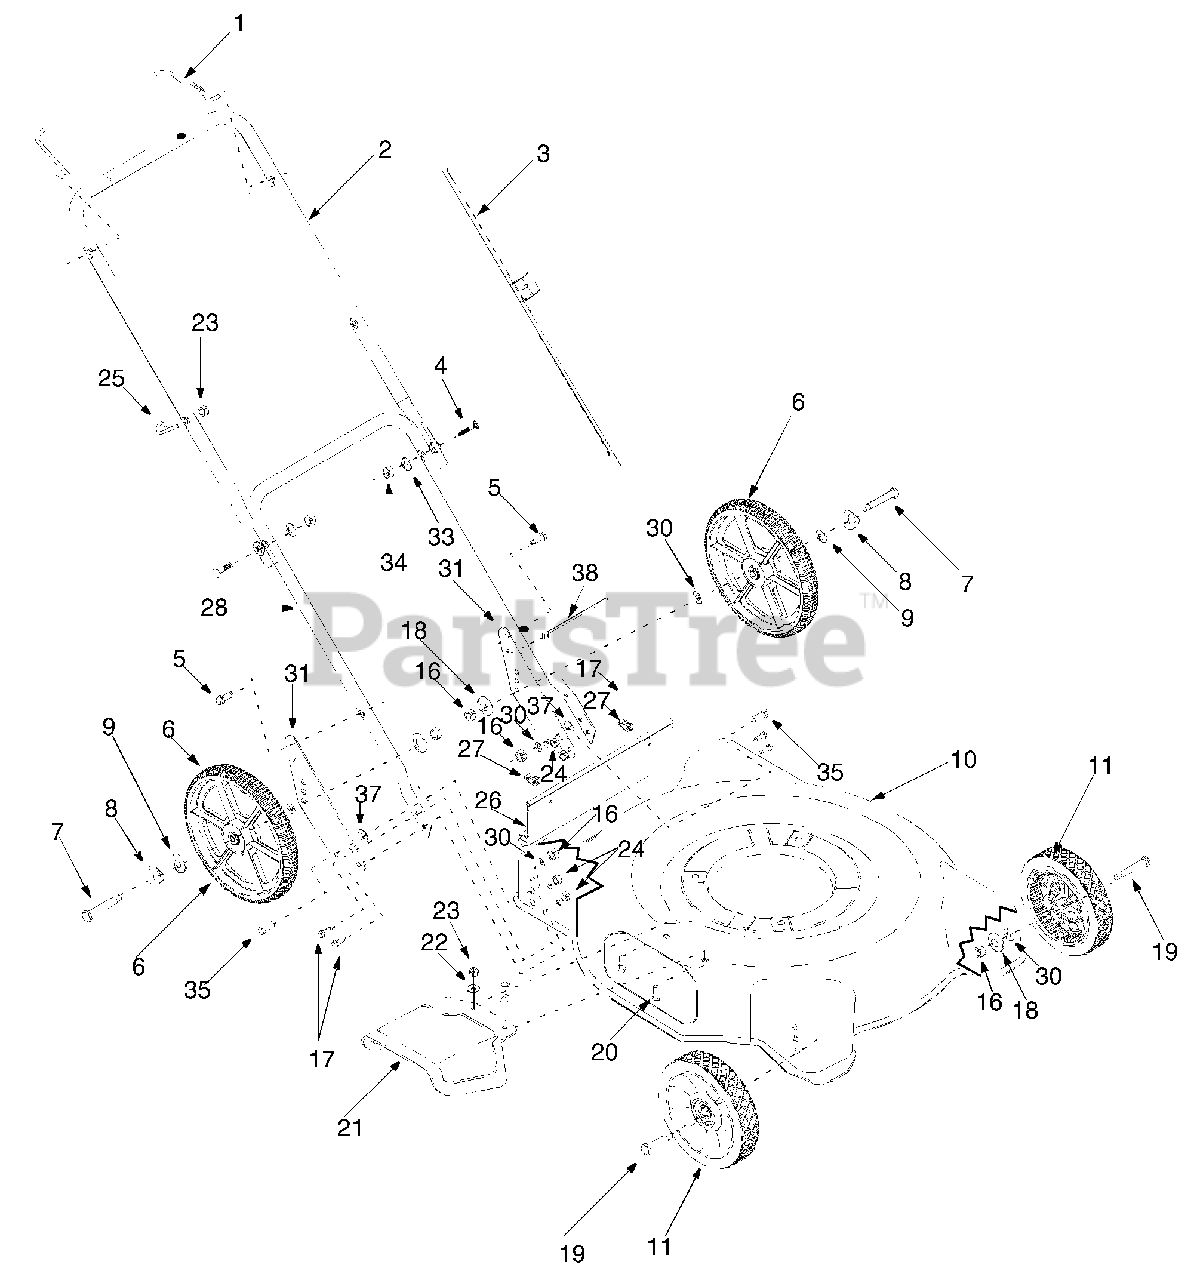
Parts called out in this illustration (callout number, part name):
4	Carriage Screw 5/16-18 x 1.5"
5	Self-Tapping Screw 5/16-12
6	Rear Wheel 14" x 1.8 Bar
7	Rear Axle Bolt
8	Spring Washer
9	Bell Washer
16	Hex Nut 3/8-16
17	Hex Bolt 5/16-18 x 0.75"
18	Bell Washer .39 I.D. x 1.13 O.D. x .062
19	Front Axle Bolt
20	Carr. Screw 1/4-20 x 1.0
21	Side-Discharge Chute
22	Flat Washer .28 I.D. x .74 O.D. x .063
23	Hex Lock Nut 1/4-20
24	Hex Flange Lock Nut 5/16-18 Gr.5
25	Rope Guide
26	Rear Trailing Shield
27	Hinge Clip
34	Hex Nut 5/16-18
35	Hex Screw 3/8-16 x .75" Gr.5
37	Flat Washer .385 x 1.0 x .135
38	Cable Tie
